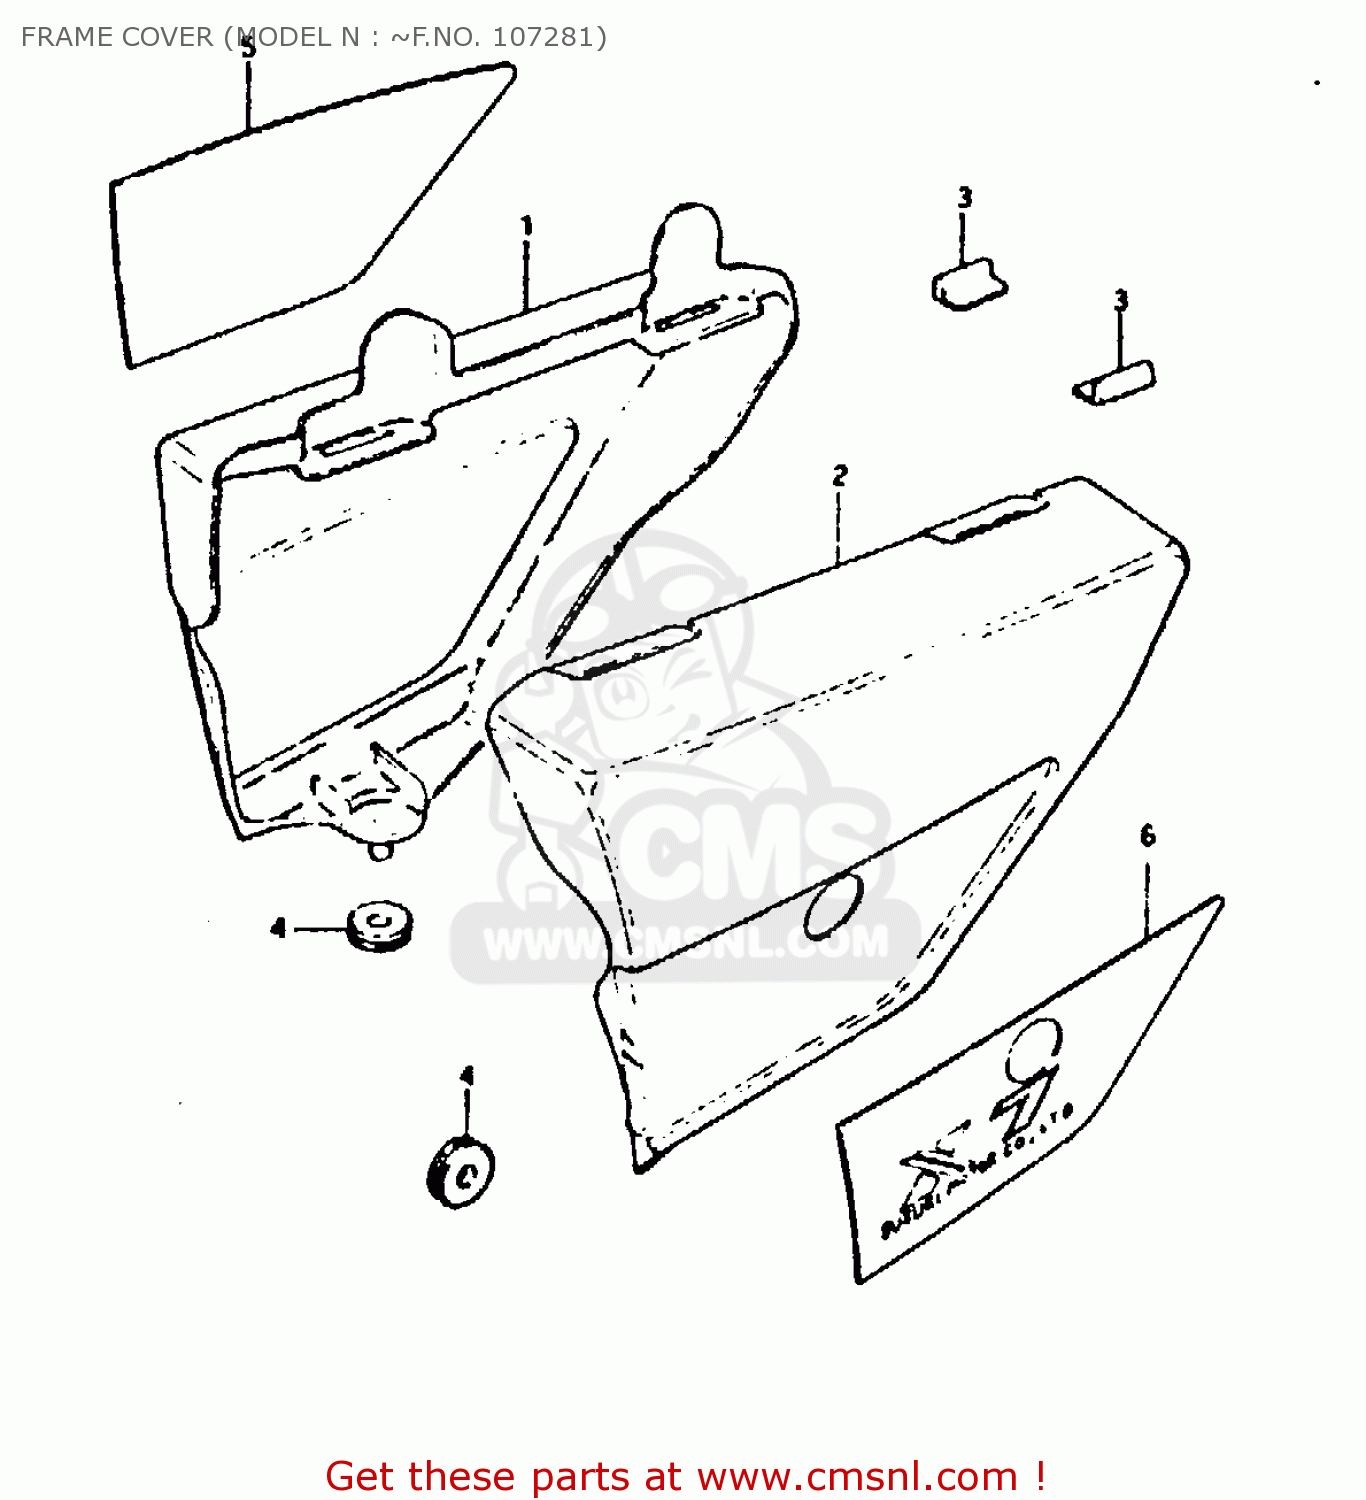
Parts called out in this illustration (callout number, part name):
1	COVER, RH (RED)
2	COVER, LH (RED)
3	CUSHION,FRAME COVER
4	CUSHION
5	EMBLEM, RH
6	EMBLEM, LH
